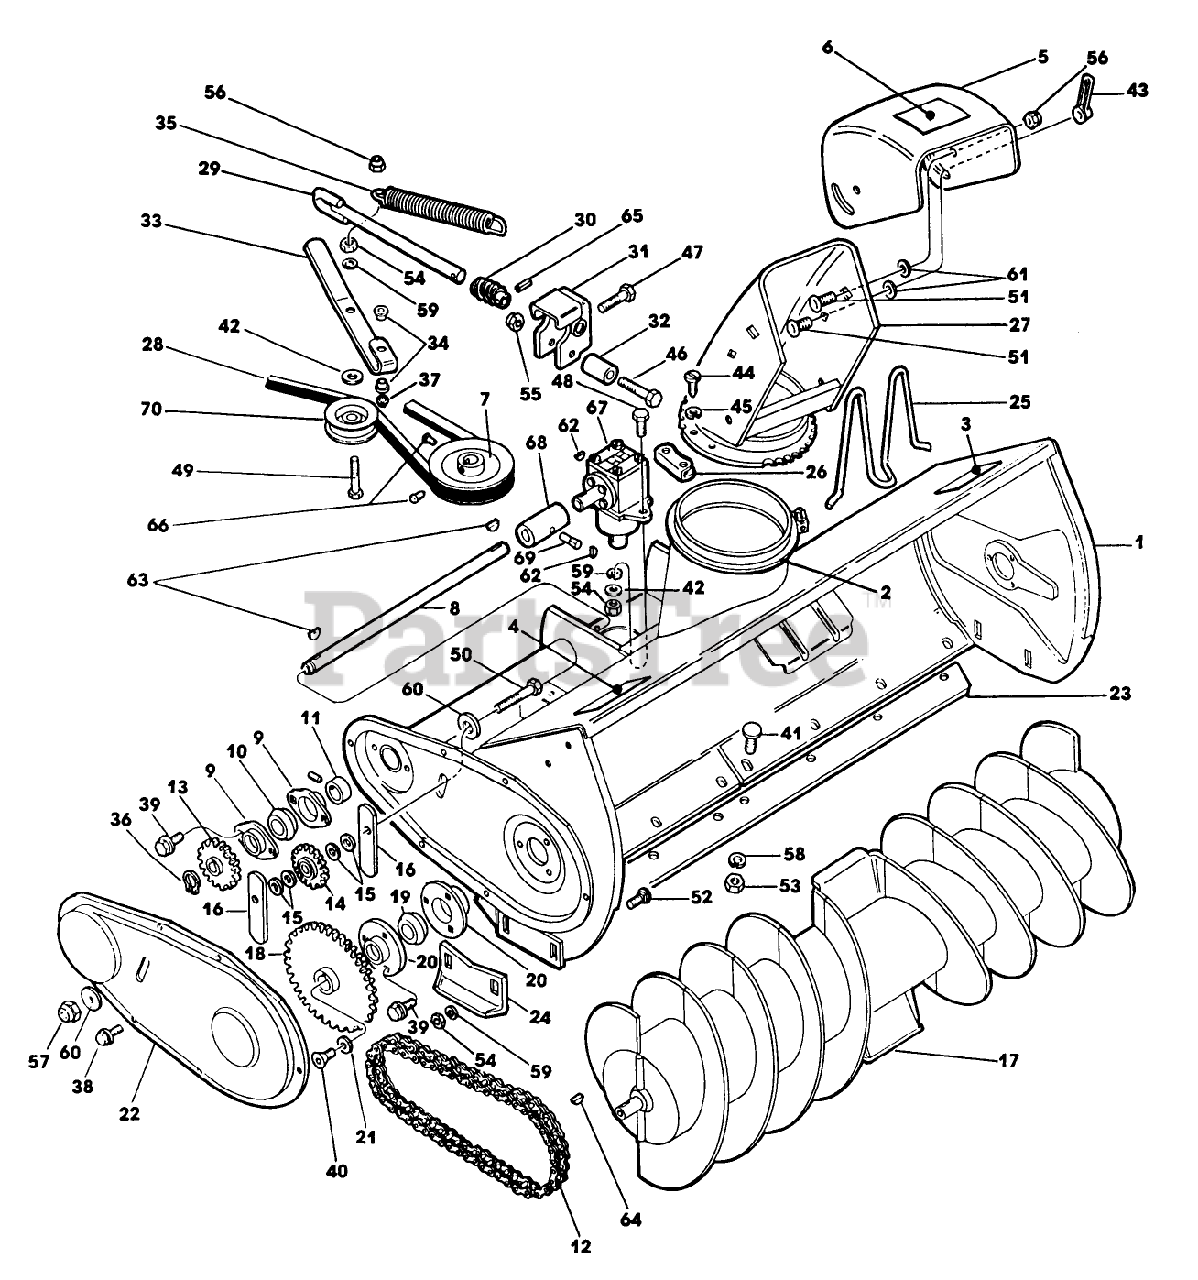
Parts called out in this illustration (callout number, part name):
7	PULLEY
9	FLANGETTE-BEARING
10	DISCONTINIUED
11	COLLAR-BEARING
13	SPROCKET ASSEMBLY
15	SPACER
24	SKID
26	RETAINER
28	V-BELT SECONDARY
34	BUSHING
36	RING-RETAINING
37	SNAP RING
42	WASHER
44	SCREW
53	NUT SS
54	NUT
55	NUT-LOCK, CONE
56	NUT-LOCKING
57	NUT-HEX CONE LOK
59	WASHER
70	PULLEY - IDLER
